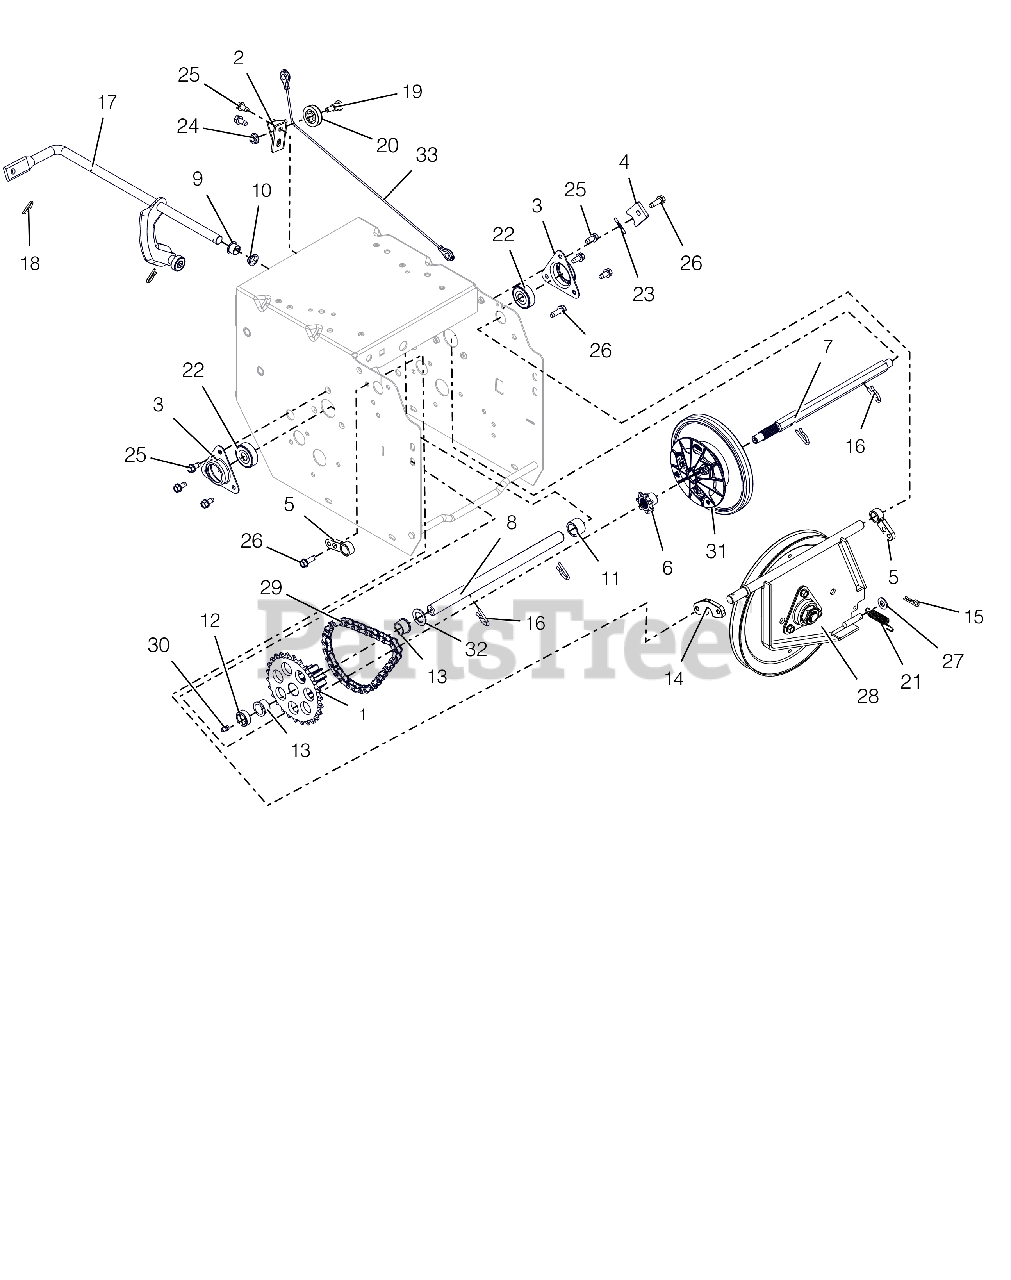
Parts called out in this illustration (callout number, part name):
1	PINION & SPROCKET
2	BRACKET, CABLE PULLEY
3	FLANGE, BEARING
4	TAB, ANTI ROTATION
5	SUPPORT BUSHING, SWING GATE
6	SPROCKET, PINION 7T W/SPLINE
7	SHAFT, HEX W/SPLINE TRACK
8	SHAFT, PINION TRACK
9	BUSHING, POLYLINER-.50 SPLIT
10	BUSHING, POLYLINER-.50 SNAPIN
11	SPACER, .635X.880X.611
12	BSHG-SLV, .635X.880X.305
13	BSHG-FLG .625X.750X.500X.875
14	SPACER, SWING GATE
15	PIN-HAIR INT .08X.18X1.18 YWZC
16	PIN, SPRING CLIP
17	ARM, SHIFT-SMALL DASH (ASSY)
18	CLIP, SPRING
19	BOLT, SHLDR-.375X.375X.25-20
20	PULLEY, CABLE
21	SPRING, EXT. .043X.438X1.64
22	BRG-BALL .437X1.375X.437
23	@PIN-GRV .125X1.00 TP E ALLOY
24	@NUT-LK-CTR-FLG .25-20 YWZC
25	SCR-TAP .25-20X.50 HWH TR YWZ
26	SCR-TAP-PM .25-20X.75 TR YWZ
27	@WSHR-FL-STL.344X.688X.065YWZC
28	PLATE, SWING - ASSEMBLY
29	CHAIN - #41, 32 PITCHES
30	ZERK,FITTING .25X.125 DRIVE IN
31	DISC, FRICTION DRIVE-ASSEMBLY
32	WSHR-FL-STL .630X1.005X.062 YZ
33	CABLE, LOWER TRACTION (CMPCT)
